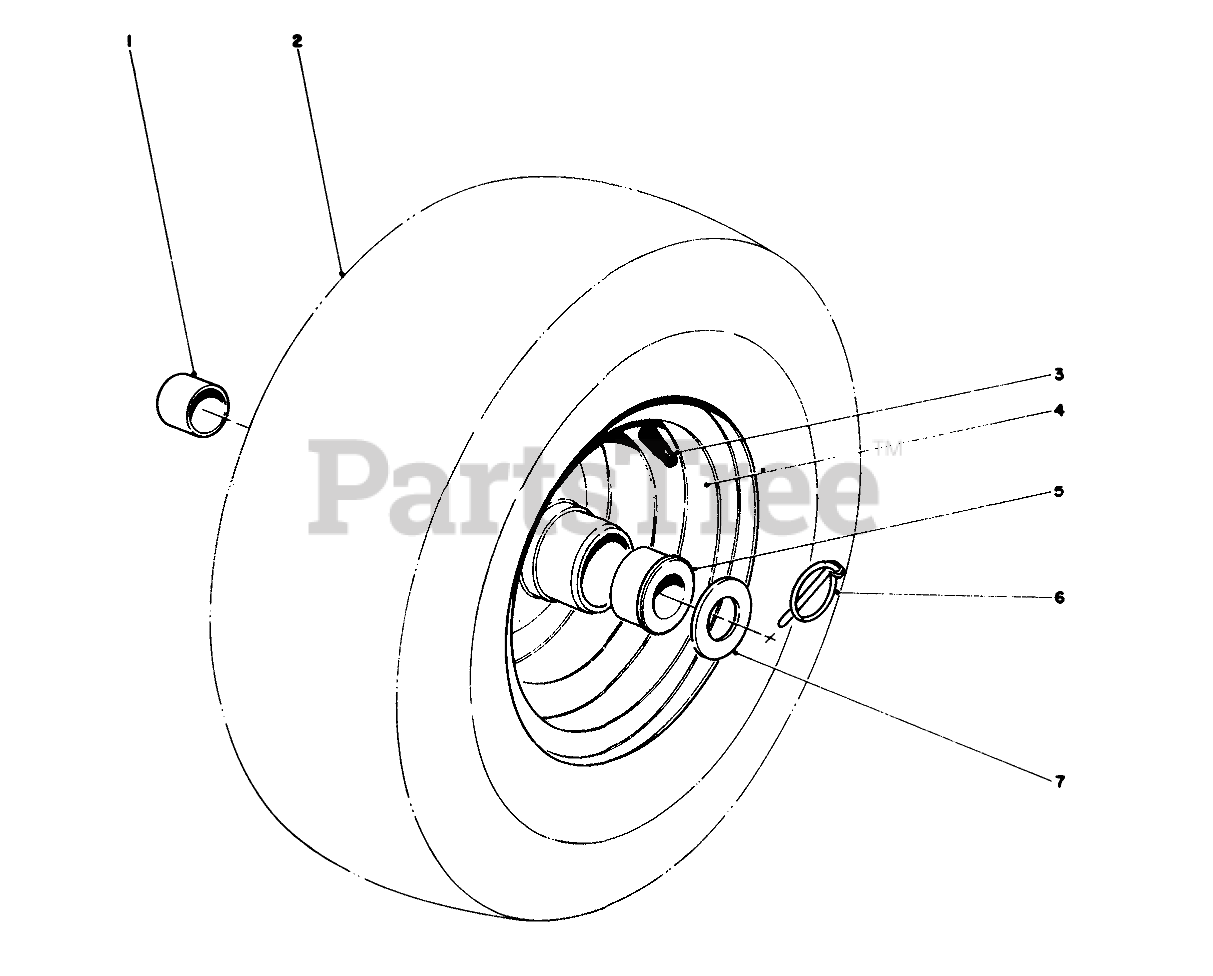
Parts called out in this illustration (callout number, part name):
1	.877ID X .750LG BSHG
2	Tire
3	STEM-VALVE
4	Wheel & Hub Assembly (Incl. Ref. #1 & 5)
5	BUSHING
6	PIN-LYNCH
7	WASHER-THRUST
